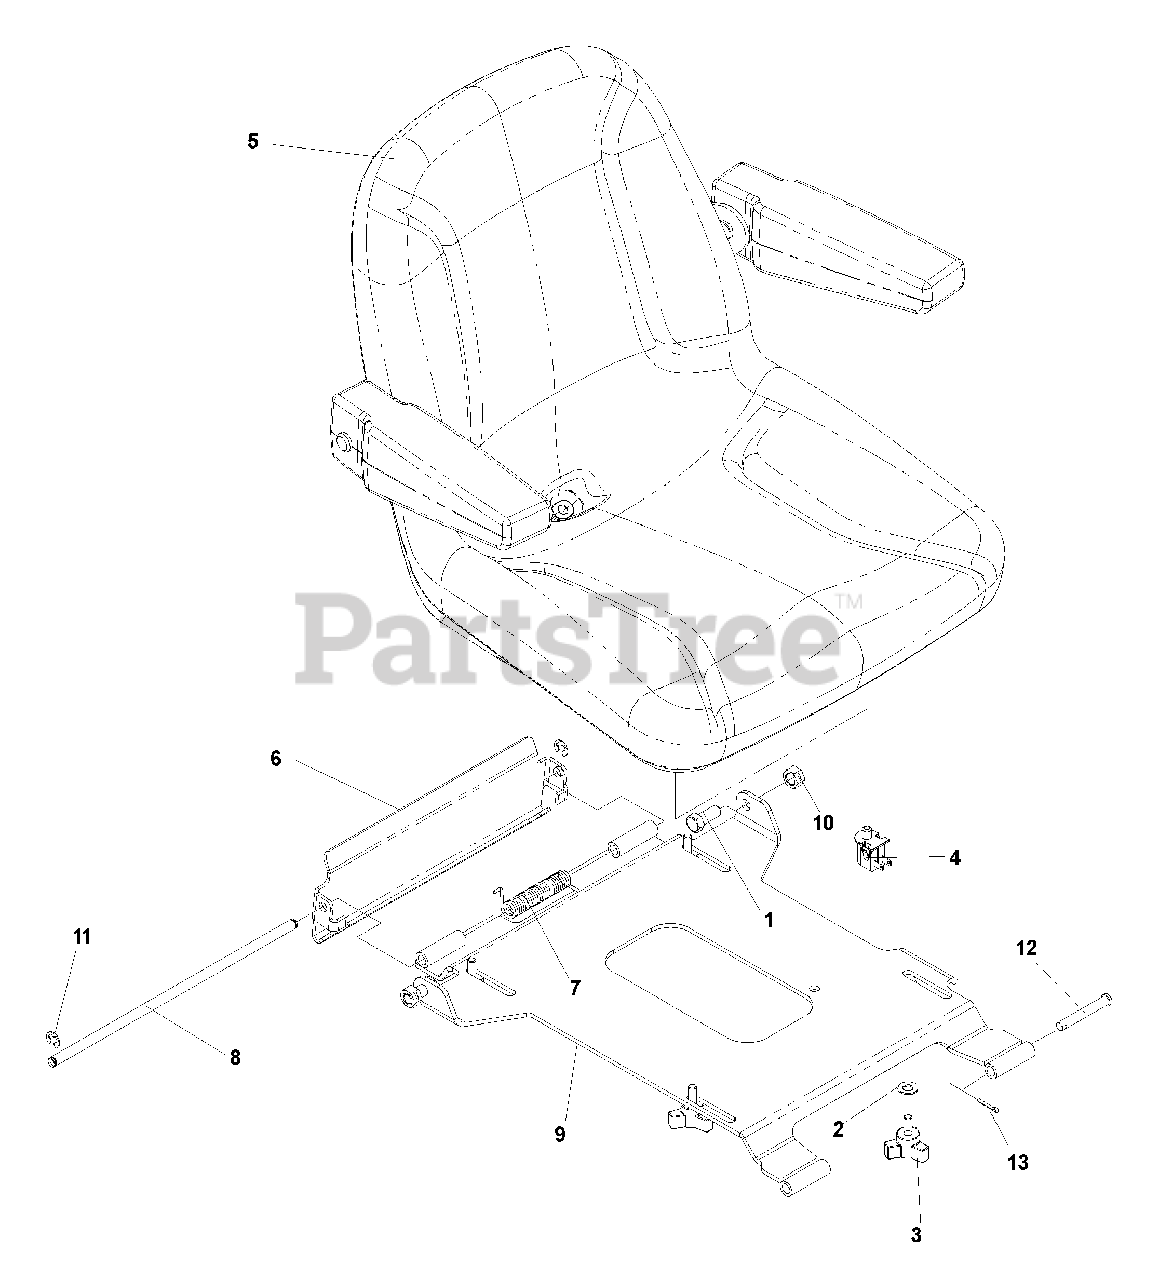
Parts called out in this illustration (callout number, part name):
1	HCS, 7/16-14 X 1, GR5
2	WASHER, 3/8, SPRING, SPEC
3	KNOB W/STUD
4	SEAT SWITCH
5	SEAT W/ARMREST
6	SEAT LATCH BRACKET
7	TORISON SPRING
8	SEAT LATCH ROD
9	SEAT MOUNT
10	NUT, 7/16-14, CENTERLOCK, GR A
11	RING-RETAINING
12	CLEVIS PIN
13	PIN, COTTER, 1/8 X 3/4
